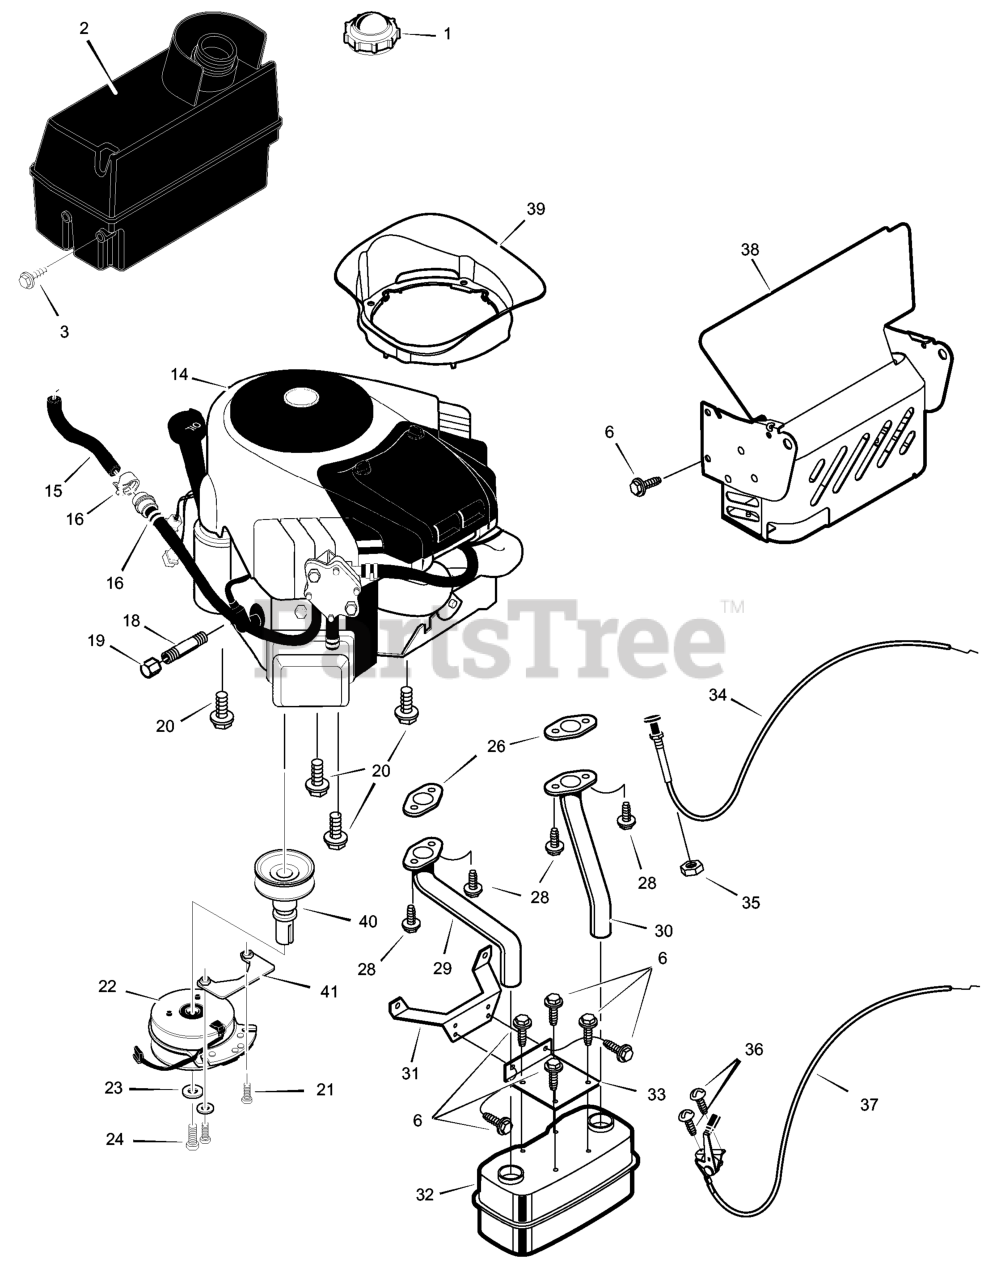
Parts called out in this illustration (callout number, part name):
1	Cap, Fuel
2	Tank, Fuel
14	Engine *
15	Fuel Line (Must cut to length)
16	Clamp
18	Pipe, Oil Drain
19	Cap, Oil Drain
20	Bolt
22	Clutch, Electric
23	Washer
29	Tube, Right Exhaust
30	Tube, Left Exhaust
31	Bracket, Muffler Mount
32	Muffler
33	Bracket, Muffler
35	Nut
37	Control, Throttle
38	Shield Assembly, Heat
40	Adapter, Pulley
41	Plate, Brake
